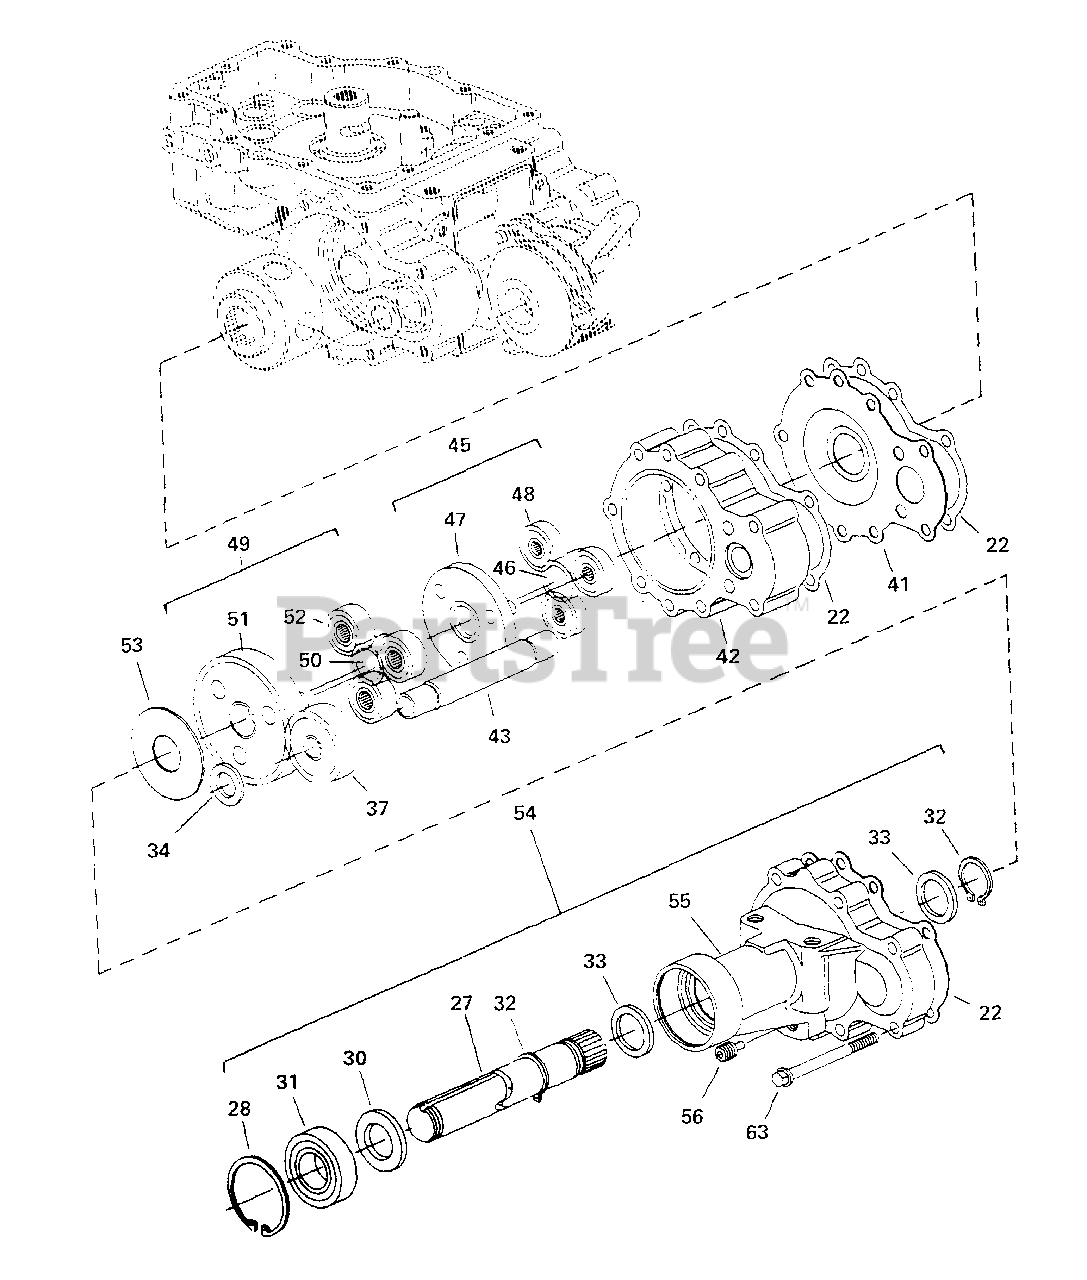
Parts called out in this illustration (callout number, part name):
22	GASKET, Axle Housing
27	SHAFT, Axle
28	RETAINING RING, Internal
30	LIP SEAL, Radial
31	BEARING, Ball
32	RING, Retainer
33	WASHER, Thrust
37	LOCK GEAR, Differential
41	PLATE, Wear
42	RING GEAR, A & B S/A, 57T
43	BRAKE SHAFT-A
45	PLANETARY GEAR, First, Subassembly (Incl. Ref. Nos. 46, 47 & 48
49	PLANETARY GEAR, Second, A & B S/A (Incl. Ref. Nos. 50, 51 & 52
53	WASHER, Thrust
54	AXLE HOUSING, S/A-A
55	HOUSING, Axle-A
56	PLUG, Magnetic
63	CAPSCREW, 1/4-20 Hex Flange x 2-3/4
63	Gasket Overhaul Kit (Incl. Ref. Nos. 19, 22 & 24)
